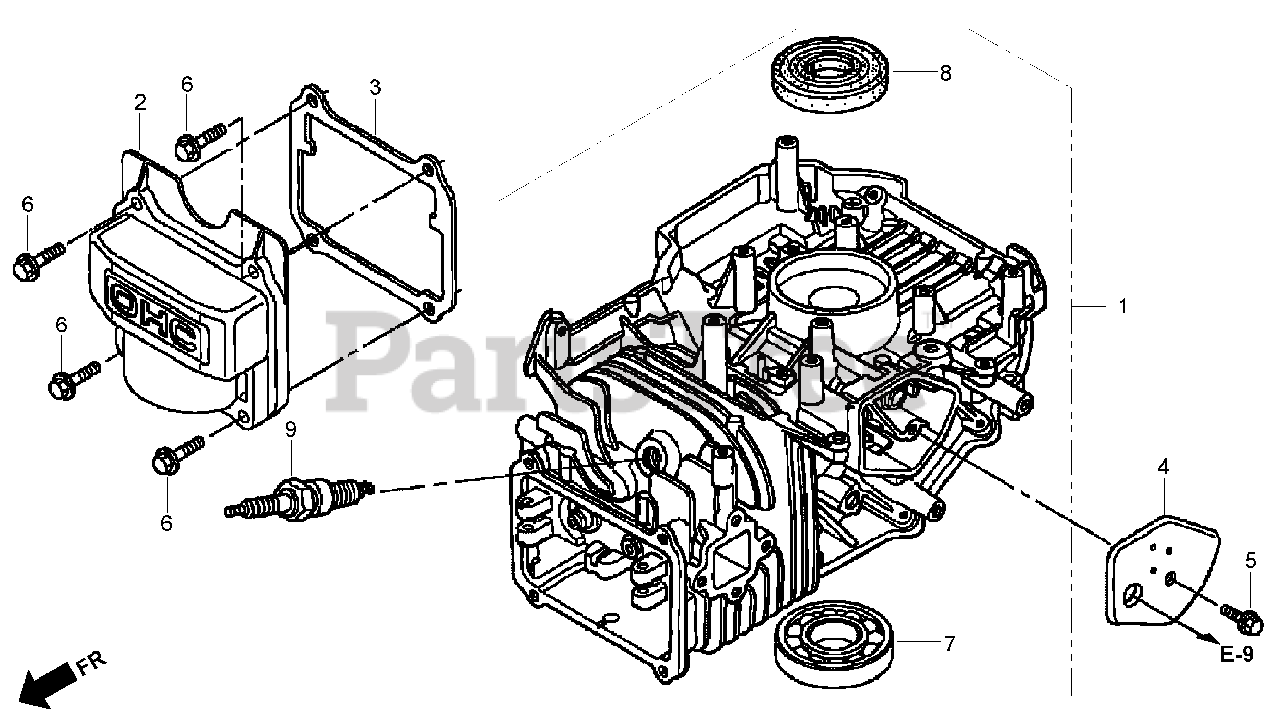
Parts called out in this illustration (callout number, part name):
1	CYLINDER ASM
2	COVER-HEAD, CYLINDER
3	GASKET-COVER, HEAD
4	COVER-BREATHER (BREATHER VALVE ASM)
5	BOLT-FLANGE (6X14) (C T200)
6	BOLT-FLANGE (6X25) (C T 200)
7	BEARING-BALL, RADIAL
8	SEAL-OIL (25.4X74X6)
9	SPARK PLUG (B P R 5E S) (N G K)
